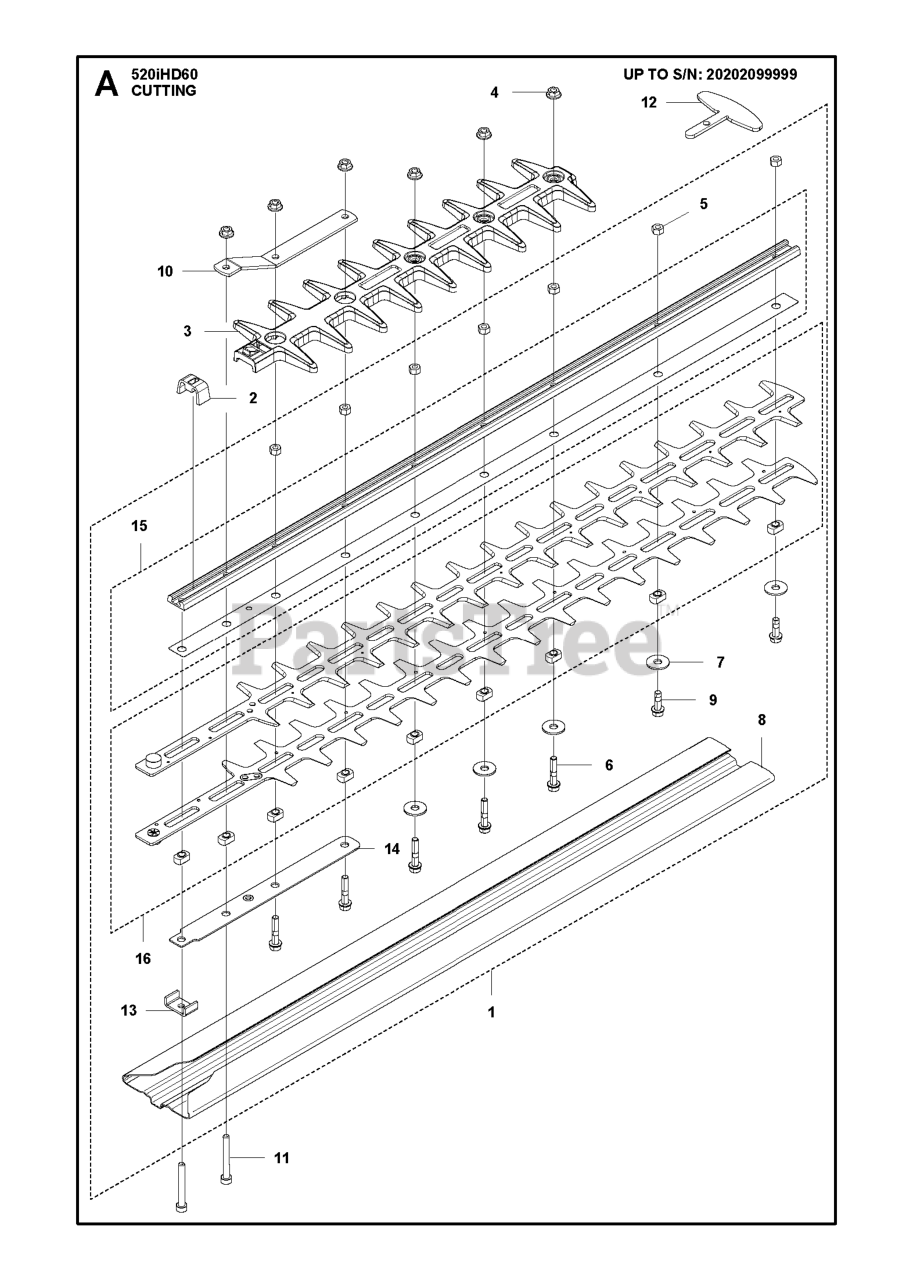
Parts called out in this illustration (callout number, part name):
1	CUTTING DECK LIHD HD60 INCR. S
3	PROTECTION ASSY BLADE
4	HEXAGON NUT FLANGE M5 8 ZN/FE
6	SCREW IHSCFM M5X25 10.9 ZN/FE
7	WASHER 6,4X18X1,5
8	TRANSPORT GUARD CUTTING DECK H
9	SCREW M5X16 T25
10	SUPPORT CUTTING DECK
11	SCREW IHSCT EN ISO 4762 / DIN
12	PROTECTION BLADE TIP
13	BRACKET
15	CUTTING DECK KIT
16	CUTTING DECK KIT
